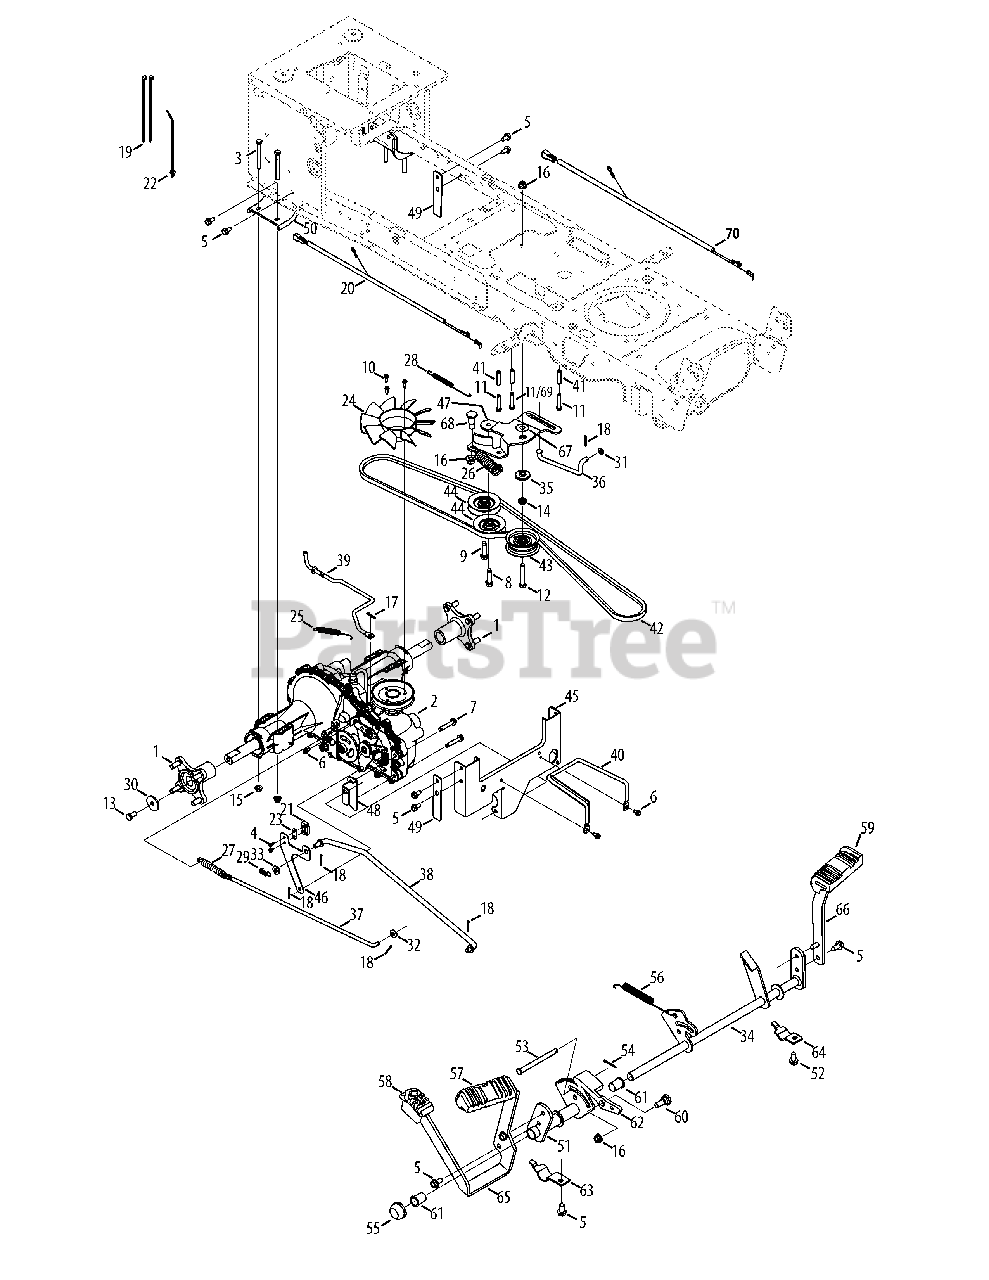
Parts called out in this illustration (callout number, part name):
1	Wheel Assembly Hub
2	Transmission
3	Hex Screw, 5/16-18:3.00
4	Screw, #8-18:0.500
5	Taptite Screw, 5/16-18:.750
6	Taptite Screw, 1/4-20:0.500
7	Taptite Screw, 5/16-18:1.750
8	Taptite Sems Screw, 3/8-16:1.500
9	Taptite Sems Screw, 3/8-16:1.875
10	Screw, #12-24:0.625
11	Taptite Screw, 1/4-20:1.625
12	Hex Screw, 3/8-16:2.25
13	Hex Screw, 3/8-16:.750
14	Jam Nut, 7/16-20
15	Flangelock Nut, 5/16-18
16	Flangelock Nut, 3/8-16
17	Cotter Pin, .072 DIA. x 1.13 LG
18	Cotter Pin, 3/32:1.0
19	Cable Tie, 3/16 x .05 x 7.4
20	Jumper Harness
21	Short Spring Switch
22	Push Mount Cable Tie 7.5 LG
23	Insulator Nut Plate
25	Extension Spring, .50 DIA x 5.0 LG
26	Extension Spring, 1.00 DIA x 4.75
27	Extension Spring, .59 OD x 4.00 LG
28	Extension Spring, .38 DIA x 5.6
29	Extension Spring, .375 OD x 1.44 LG
30	Flat Washer, .390 x 1.500 x .134
31	Flat Washer, .330 x .630 x .0635
32	Flat Washer, .344 x .750 x .120
33	Flat Washer, .407 x .812 x .135
34	Brake Control Assembly
35	Shoulder Spacer, 1.375 x .380 x .183
36	Footpedal Bypass Transmission Rod
38	Control Rod
39	Disengage Rod
40	Belt Keeper, 5/16
41	Spacer, 260 x .372 x 1.420 LG
42	V Belt, 4L x 77.0
43	Flat Idler Pulley, 2.75 OD
44	V Idler Pulley, 3.06
45	Torque Bracket
46	Switch Bracket
47	Center Idler Bracket
49	Plate Bracket
51	Hydro Pedal Bracket Assembly
52	Taptite Screw, 5/16-18:0.625
53	Clevis Pin, 5/16 x 3.985
54	Bow-Tie Cotter Pin
56	Extension Spring, .63 DIA x 4.95 LG
57	Pad, Pedal, Forward
58	Pad, Pedal, Reverse
59	Pad, Pedal, Brake
60	Shoulder Bolt, .500 x .270:3/8-16
61	Flange Bearing, .630 ID x .695 OD x .60
62	Cruise Latch
63	Pedal Support Bracket
64	Pedal Support Bracket, 5/8
65	Bracket, Pedal, Drive Hydro
66	Brake Pedal Bracket
67	Screw, Shldr, .50 x .685 3/8-16
68	Washer, Flat, .385 x 1.0 x .030
69	Taptite Screw, 1/4-20:1.75
70	Jumper Harness, Ground & Reverse
